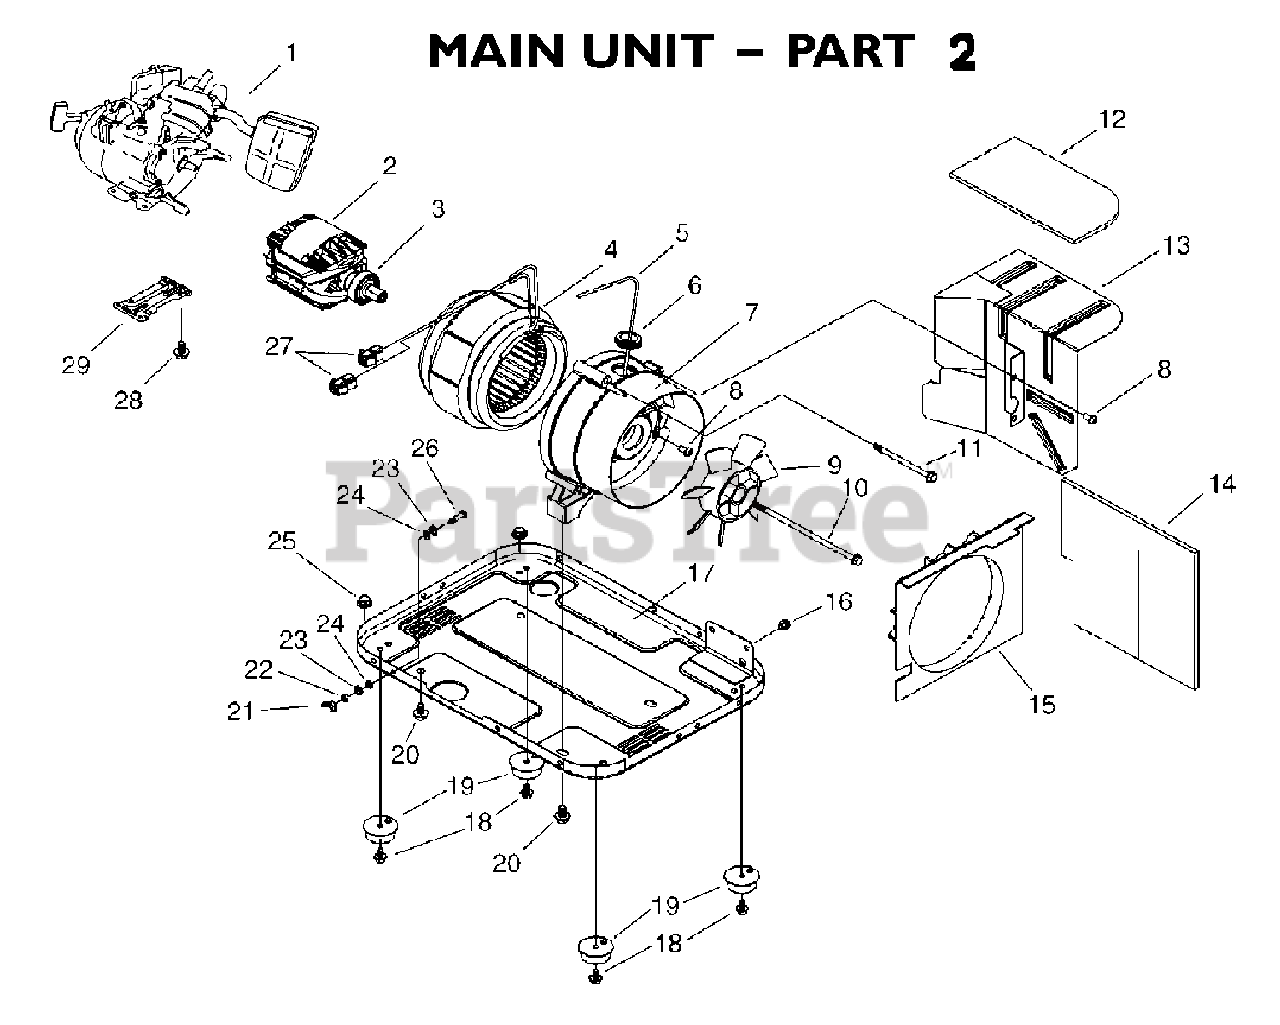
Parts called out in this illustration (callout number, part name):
5	LEAD, GREEN
6	BUSHING, LEAD WIRE, G790B
8	SCREW, SELF TAP, M6-12
9	FAN, COOLING
10	BOLT, RTR
11	BOLT, STATOR
12	INSLTN, HEAT SEALED, #1
13	MFFLR, SEALED
14	INSLTN, HEAT SEALED, #2
15	DUCT, AIR
16	PHMS, M6-1.0,W/L/FW
17	BASE, GEN
18	BOLT, FLNG, M6-1.0 X 10
19	MNT,VIBR
20	HHCS, FLNG, M8-1.25 X 12
21	NUT,WING, M5 X 0.8
22	NUT, M5 X 0.8
23	WSHR, LOCK
24	WSHR, FLAT
25	NUT, M8-1.25, FLANGE
26	PHMS, M5-0.8 X 20
27	CONNECTOR
28	HHCS, FLNG
29	STND, ENG
